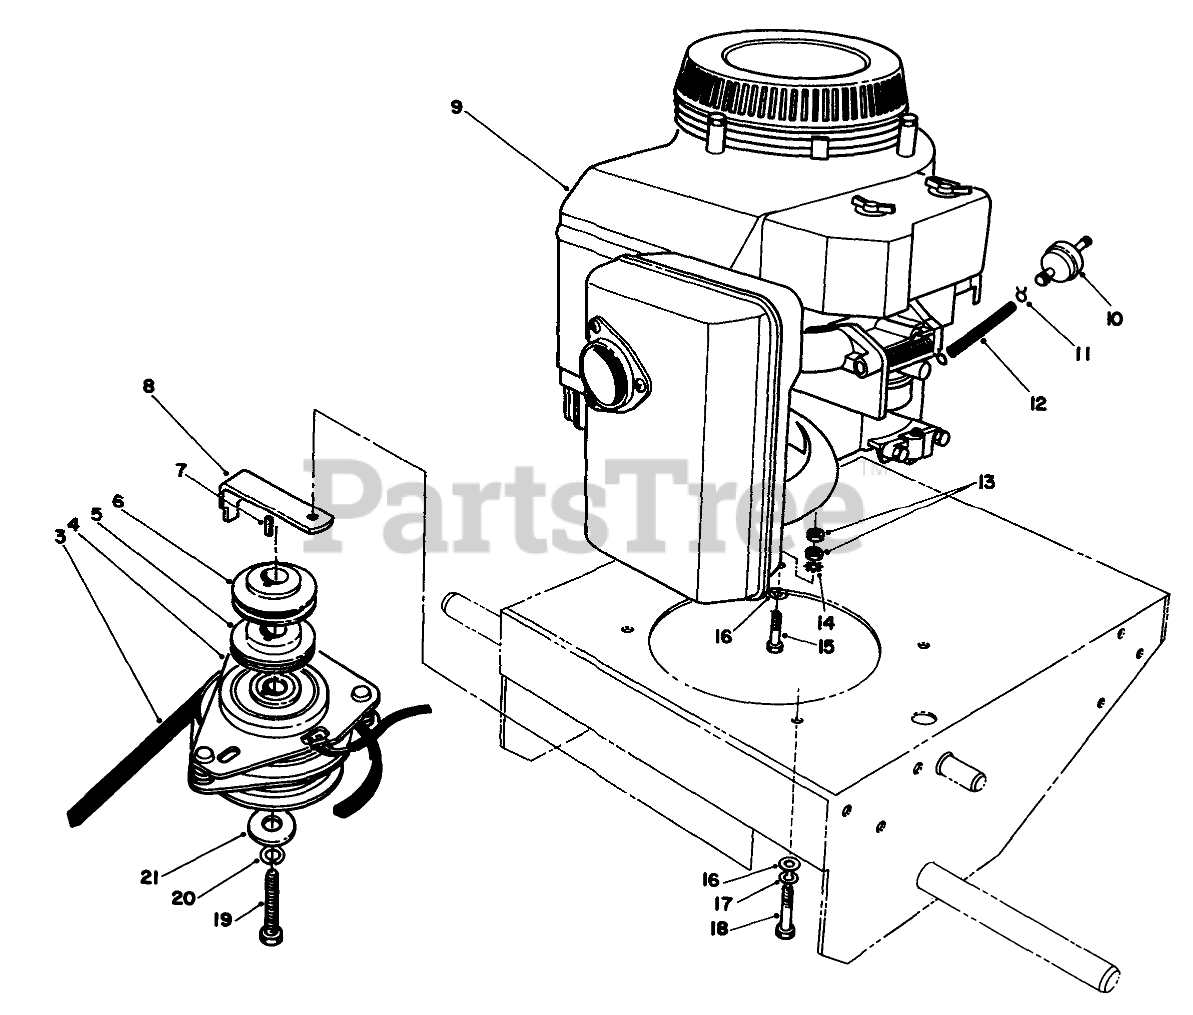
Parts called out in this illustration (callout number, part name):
3	V-BELT, DRIVE
4	CLUTCH/BRAKE
5	SHEAVE-LOWER HALF
6	SHEAVE-UPPER HALF
7	KEY-SQUARE
8	Retainer-Clutch
10	FILTER-FUEL
11	CLAMP-HOSE
12	HOSE-FUEL
13	NUT-JAM
14	WASHER-LOCK
15	SCREW (ENGINE, GROUND)
16	WASHER-PLAIN
17	WASHER-LOCK
18	SCREW-HH
19	SCREW-CLUTCH
20	WASHER-LOCK
21	WASHER-CLUTCH
